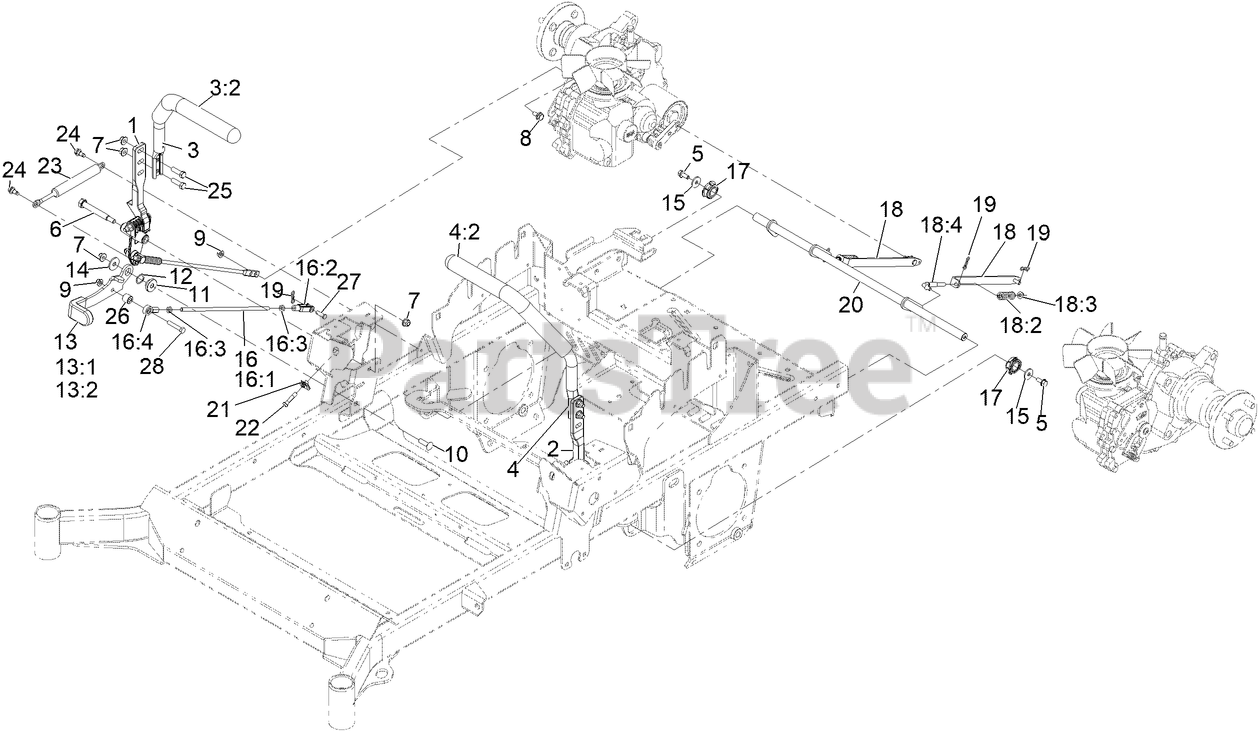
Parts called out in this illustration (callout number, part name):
1	ASM, MOTION CONTROL RT
2	ASM, MOTION CONTROL LT
3	RH HANDLE ASM
3:2	GRIP-LEVER, CONTROL
4	LH HANDLE ASM
4:2	GRIP-LEVER, CONTROL
5	SCREW-HHF
6	BOLT-PIVOT
7	NUT-HF, NI
8	BOLT-SHOULDER,HFH
9	NUT-HF, NI
10	Bolt-Carriage 3/8-16 X 1 1/4
11	PIVOT-FLANGE
12	WASHER-WAVE
13	LEVER-BRAKE
13:1	Lever-Brake
13:2	GRIP-LEVER
14	WASHER
15	WASHER-FLAT
16	ASM, Front Brake Link
16:1	Linkage, Brake-Front
16:2	YOKE-ADJUSTABLE
16:3	NUT-JAM
16:4	BALLJOINT-RH
17	Bearing-Spherical
18	ASM, Brake Link
18:2	Spring, Compression
18:3	NUT-HF, NI
18:4	Link, Brake
19	PIN-COTTER, LOCKING
20	WELD, BRAKE SHAFT
22	Screw-HSBH, Patch
24	SCREW-SHOULDER
25	SCREW-HH
27	PIN-CLEVIS
28	SCREW-HH
